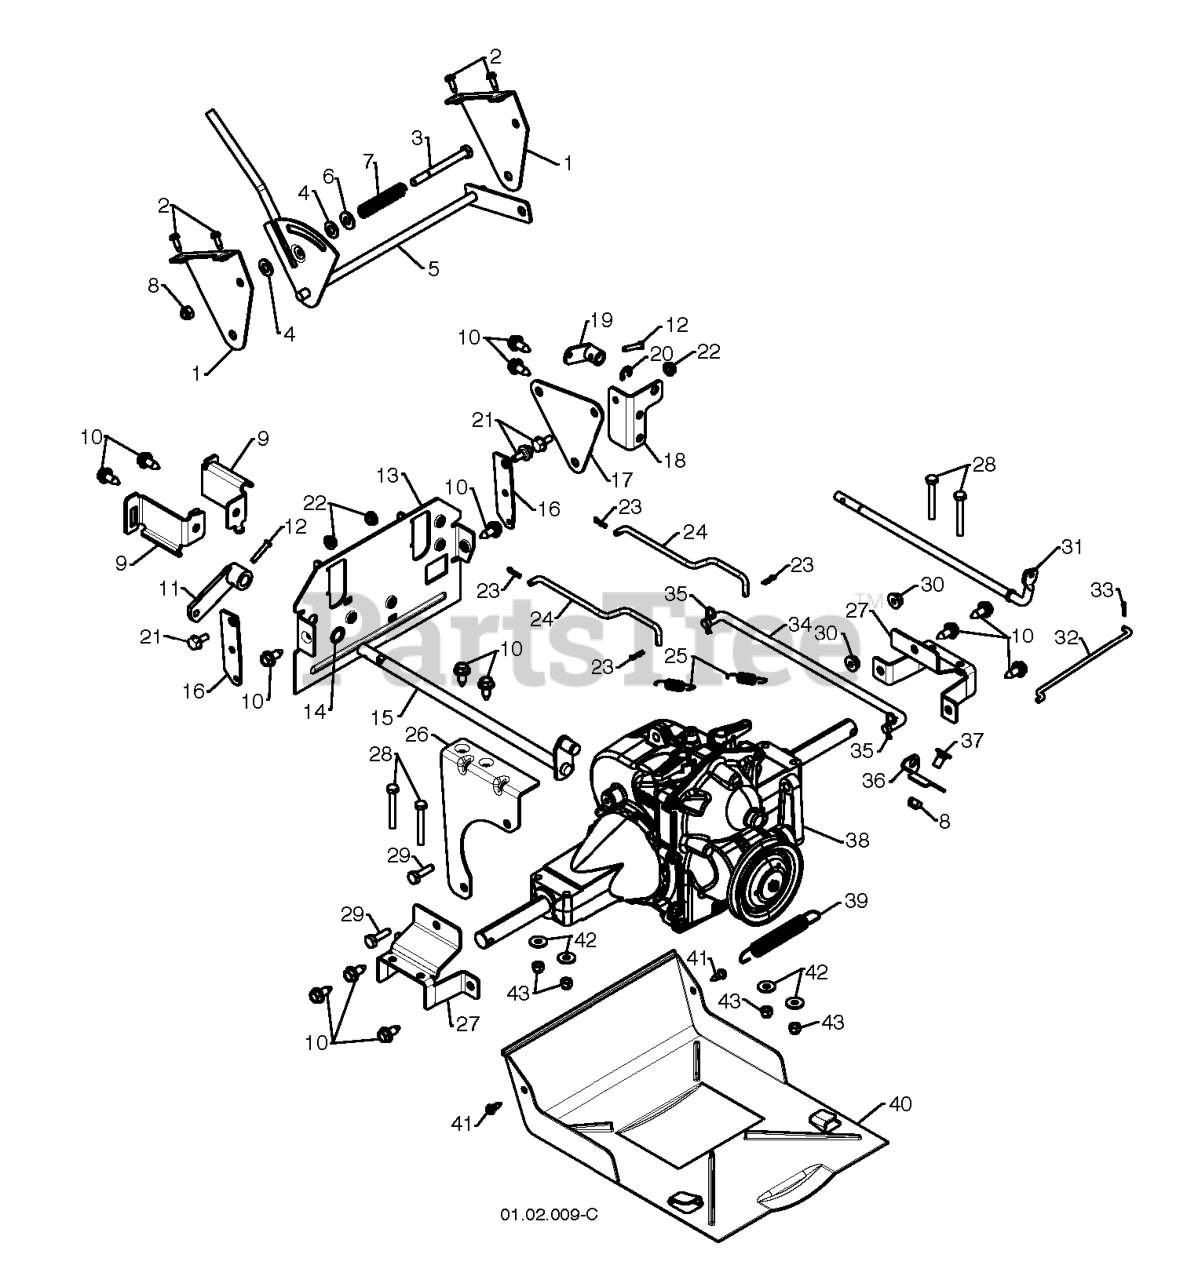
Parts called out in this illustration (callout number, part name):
1	BRACKET, SHIFT
2	SCREW #10-24 X 5/8
3	SCREW 5/16-18 X 3.25
4	WASHER, NYLON FRICTION
5	CONTROL.WLD.HYD.II
6	WASHER.20X8.5
7	SRPING.FRICTION.HYDRO
8	NUT.71038.31-18.HEX.NYLOCK
9	BRACKET.CABLE.HYDRO
10	BOLT.HEX.HD.WASHER.5/16-18X.75
11	ARM, AUGER CONTROL
12	CLEVIS PIN
13	PLATE.REAR.HYDRO.PNT.ORANGE
14	THRUST WASHER
15	CONTROL.SHAFT.ASM
17	BRACKET.SPEED.PIVOT.
18	BRACKET.SPEED.PIVOT
19	ARM.HYD.CLUTCH
20	E-RING.RETAINER.REINFORCED.375
21	BOLT.SHOULDER.3/X.25
22	NUT.HEX.FLANGE.1/4
23	COTTER PIN (3 2)(2 2MC)
24	ROD.STEER.HYD
25	SPRING.RETURN
26	BRACKET.HYDRO.STABILIZER
27	BRACKET.TRANSMISSION.MOUNT
28	BOLT.HEX.1/4-20X2.00.HEX.HD.
29	BOLT RB
30	NUT.LOCK.5/16-18
31	SHAFT.HYD.CLUTCH
32	RP ROD.HYD.CLUTCH
33	RETAINER CLIP
34	ROD.SPEED.CONT.HYD.SNOW
35	SPRING RETAINER
36	FRONT CLUTCH BRACKET
37	BOLT.CARRIAGE.5/16-18X
38	TRANSAXLE HYDRO.II PS 71876
39	SPRING, BRAKE
40	PAN.BOTTOM.PLASTIC.SNOW
41	SCREW, HEX HEAD, TAPPING
42	WASHER
43	LOCKNUT.NYLOC.1/4-20
